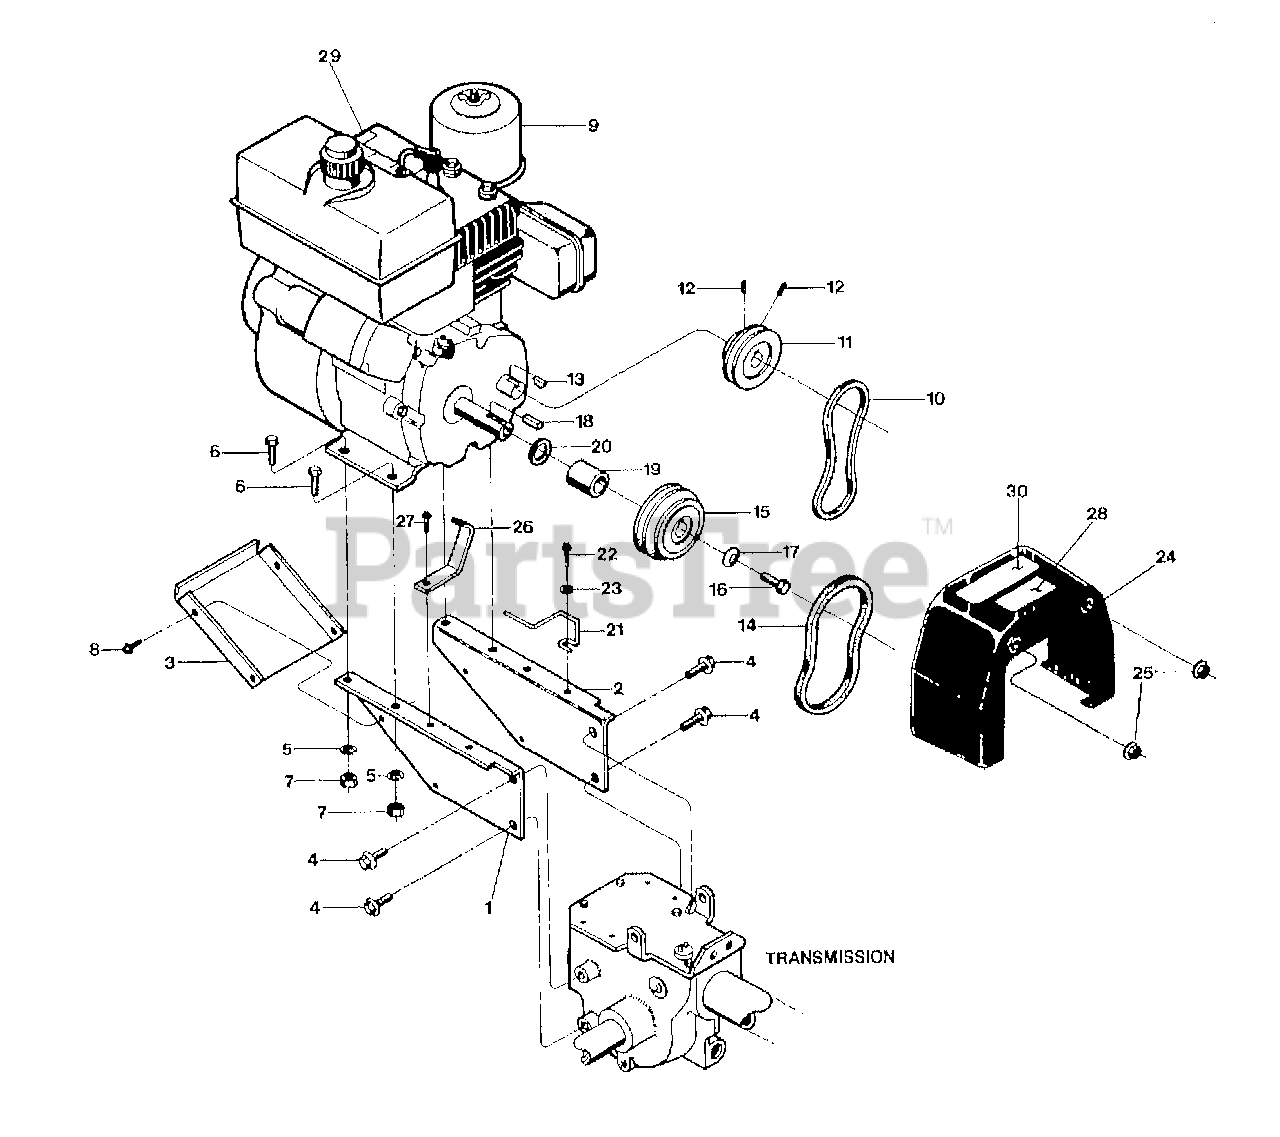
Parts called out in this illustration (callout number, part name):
1	BRKT-ENG LT P4
2	BRKT-ENG RT PNT
3	PAN-ENG BRKT PNT
4	SCR-HFLK 5/16-18X.75 ZP
5	WASHER-LK .312 ZP
6	SCR-HHC 5/16-18X.75 GR 5 ZP
7	NUT-HEX 5/16-18 ZP
8	SCR-HH SEMS 10-32x.5 ZP (W/PERMANENT WASHER)
9	ENGINE, TECUMSEH, 6HP RECOIL START, MODEL H60 TYPE 75505N SOLID STATE ELEC. IGN.
9	ENGINE, TECUMSEH, 6HP RECOIL START, MODEL H60 TYPE 75506N SOLID STATE ELEC. IGN.
10	BELT-V REV DR ECONO (SEE V-BELT SET BELOW)
11	PULLEY-REV MACH
12	SCR-SS 1/4-20 X .25 (SECURES REVERSE ENGINE PULLEY)
13	KEY-WOODRUFF #5
14	BELT-V GROOVE FWD SMFRAME (SEE V-BELT SET BELOW)
15	PULLEY-ENGINE MACH
16	SCR-HH 3/8-24X1.0 G5 ZP
17	WASHER-.994X.413X.145
18	KEY-.188 SQX1.0
19	SPACER-.937X.755X.938
20	SHIM-1.0X.7656X.031
21	GUIDE-BELT FWD
22	SCR-HWH 1/4-20 X .75 STH
23	WASHER-FLAT 1/4 SAE
24	COVER-BELT W/DECALS (INCL. 28 & 30)
25	NUT-HFLK 5/16-18 ZP (WHIZ-STYLE)
26	GUIDE-BELT REV PNT
27	SCR-HWH 1/4-20 X .5 STH
28	DECAL-BELT CHG ECONO OPC
29	DECAL-STARTING STABIL
30	DECAL-BELT COVER OPC
